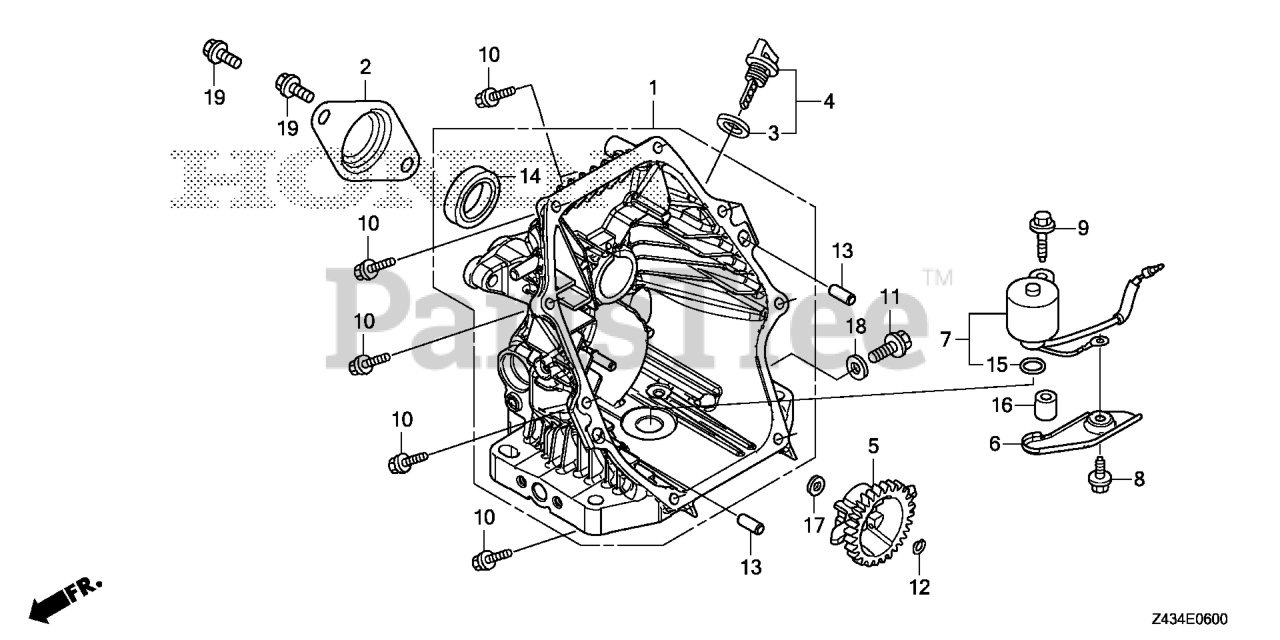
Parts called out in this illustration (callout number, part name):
1	COVER ASSY., CRANKCASE
2	GUARD, SHAFT
3	GASKET, OIL FILLER CAP (NOT AVAILABLE)
4	GAUGE ASSY., OIL LEVEL
5	HOLDER, GOVERNOR WEIGHT
6	PROTECTOR, SWITCH
7	SWITCH, OIL LEVEL
8	BOLT, FLANGE (6X14)
9	BOLT, FLANGE (6X28) (CT200) Use up to Engine SN 1530314.
10	BOLT, FLANGE (6X25) Use up to Engine SN 2056819.
11	BOLT, DRAIN PLUG
12	CLIP, GOVERNOR HOLDER
13	PIN, DOWEL (8X20)
14	OIL SEAL (28X41.25X6)
15	O-RING (11.8X2.4)
16	COLLAR (6.6X13.8X14.5)
17	WASHER, PLAIN (6MM)
18	WASHER, DRAIN PLUG (12MM)
19	BOLT, FLANGE (8X14)
